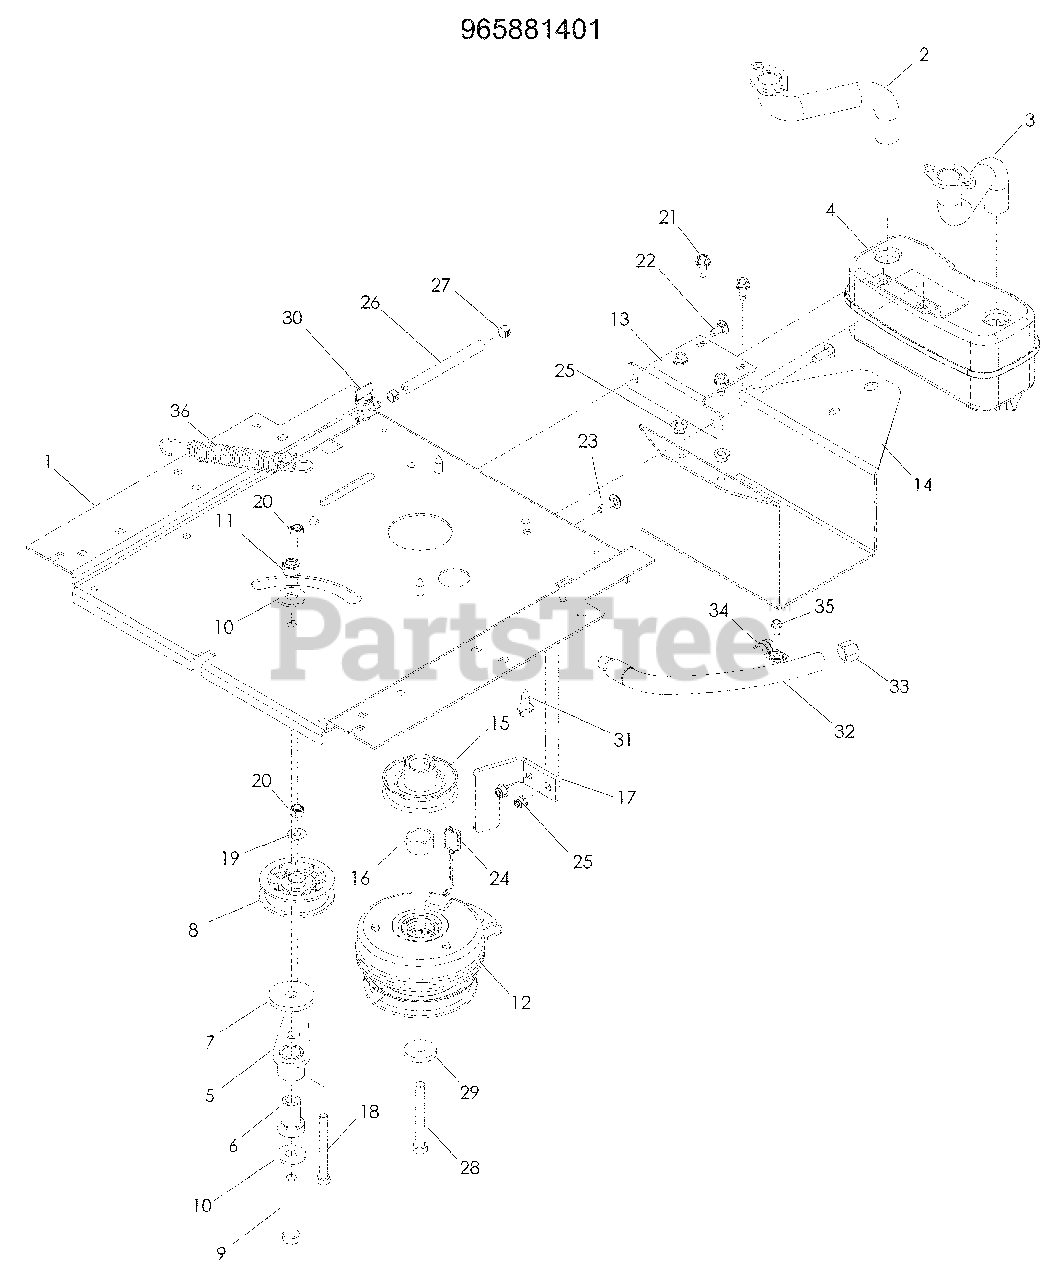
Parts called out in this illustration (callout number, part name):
1	PLATE, ENGINE
2	EXHAUST TUBE, RT
3	EXHAUST TUBE, LT
4	MUFFLER ASM TWIN
5	IDLER ARM
6	SPINDLE, IDLER
7	WASHER, HEAVY
8	PULLEY, IDLER
9	HCS ½-13 x 3¼
10	WASHER ½ FLAT
11	NUT ½ HEX NYLOC
13	BRACKET, MUFFLER
14	GUARD, MUFFLER
15	PULLEY, ENGINE
17	STOP, CLUTCH
18	HCS 3/8-16 x 3½ TPBLT
19	WASHER 5/16 STD FLT
20	NUT 3/8-16 HEX NYLOC
21	BOLT 5/16-18 x ¾ THD FRM
22	RHSNB 5/16-18 x ¾
23	RHSNB 5/16-18 x 1
24	HARNESS, CLUTCH
25	NUT 5/16-18 FLANGE NYLOC
26	FUEL LINE 5"
27	HOSE CLAMP
28	HCS 7/16-20 x 3½
29	WASHER, CLUTCH
30	VALVE, FUEL
31	HHFS 3/8-16 x 1 THD FRM
32	HOSE, DRAIN
35	SCREW ¼-20 x 5/8 SLF TAP
36	SPRING, DECK DRIVE
